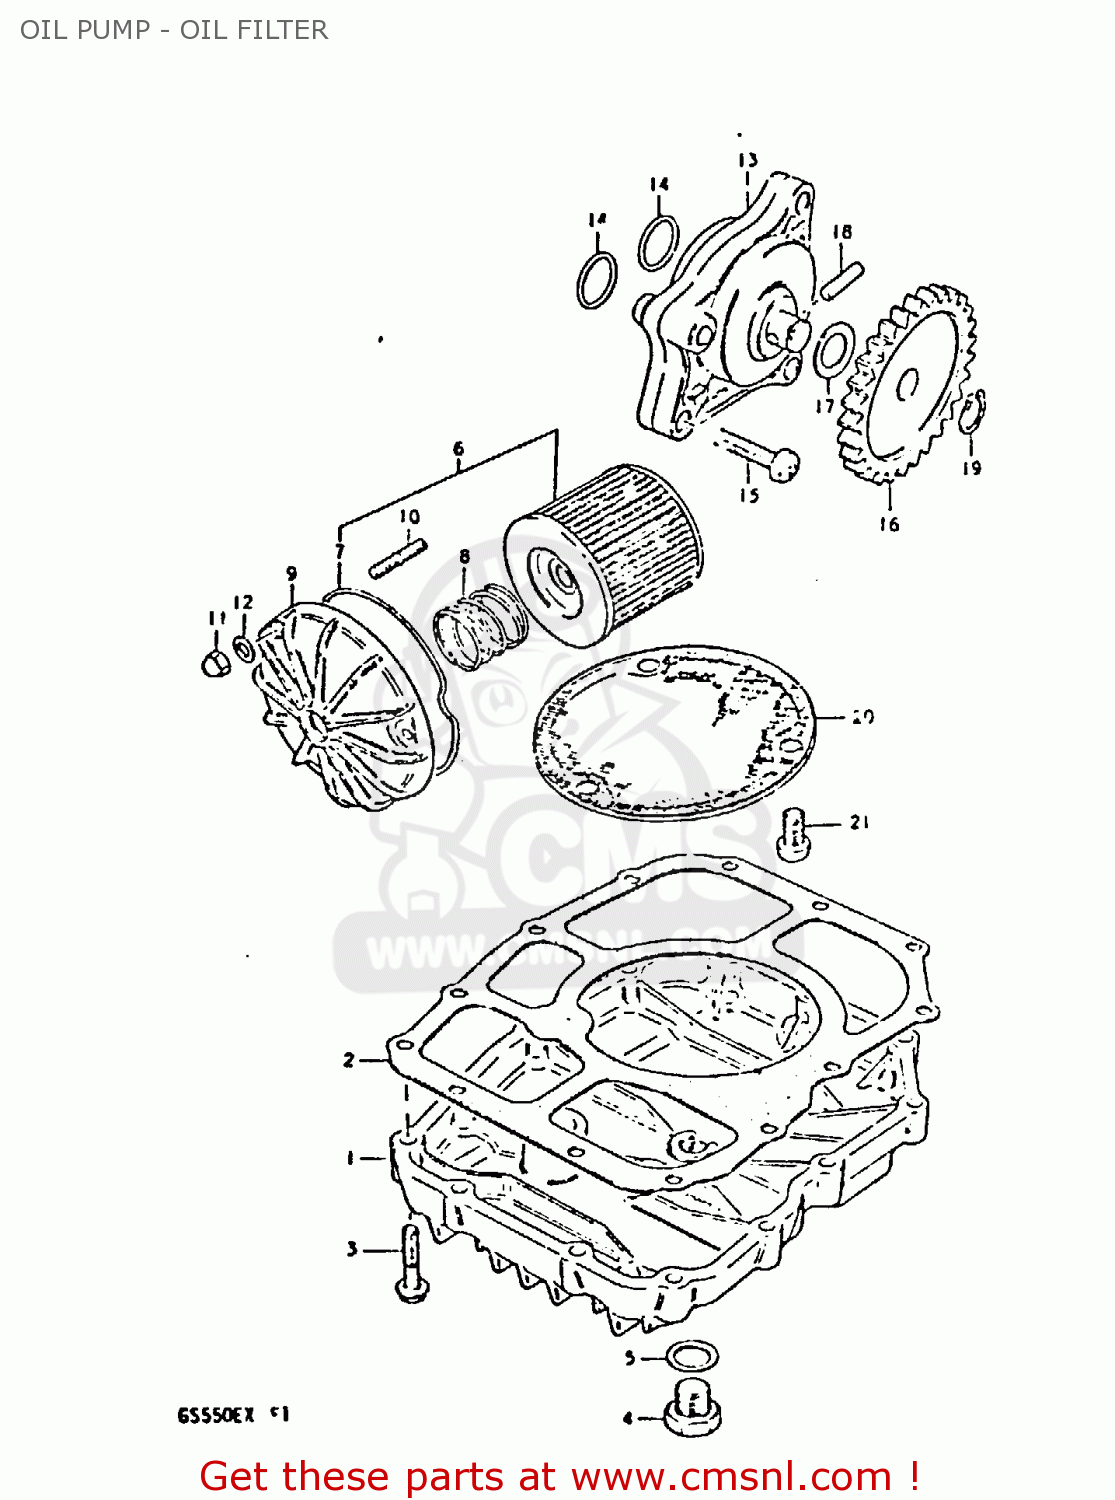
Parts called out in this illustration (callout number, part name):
1	PAN,OIL
2	GASKET,OIL PAN (MCA)
3	BOLT
4	PLUG
5	GASKET(14X19.2X2) (NAS)
6	ENGINE OIL FILTER SET
7	O RING,OIL FILTER CHAMBER CAP
8	SPRING
9	CAP,ENGINE OIL FILTER
10	STUD 6X20
11	NUT
12	WASHER
13	PUMP ASSEMBLY,ENGINE OIL
14	O RING(D:1.9,ID:13)
15	SCREW
16	GEAR,OIL PUMP DRIVEN
17	SHIM
18	PIN(4X15.8)
19	CIRCLIP
20	STRAINER,ENGINE OIL
21	SCREW 6X12
